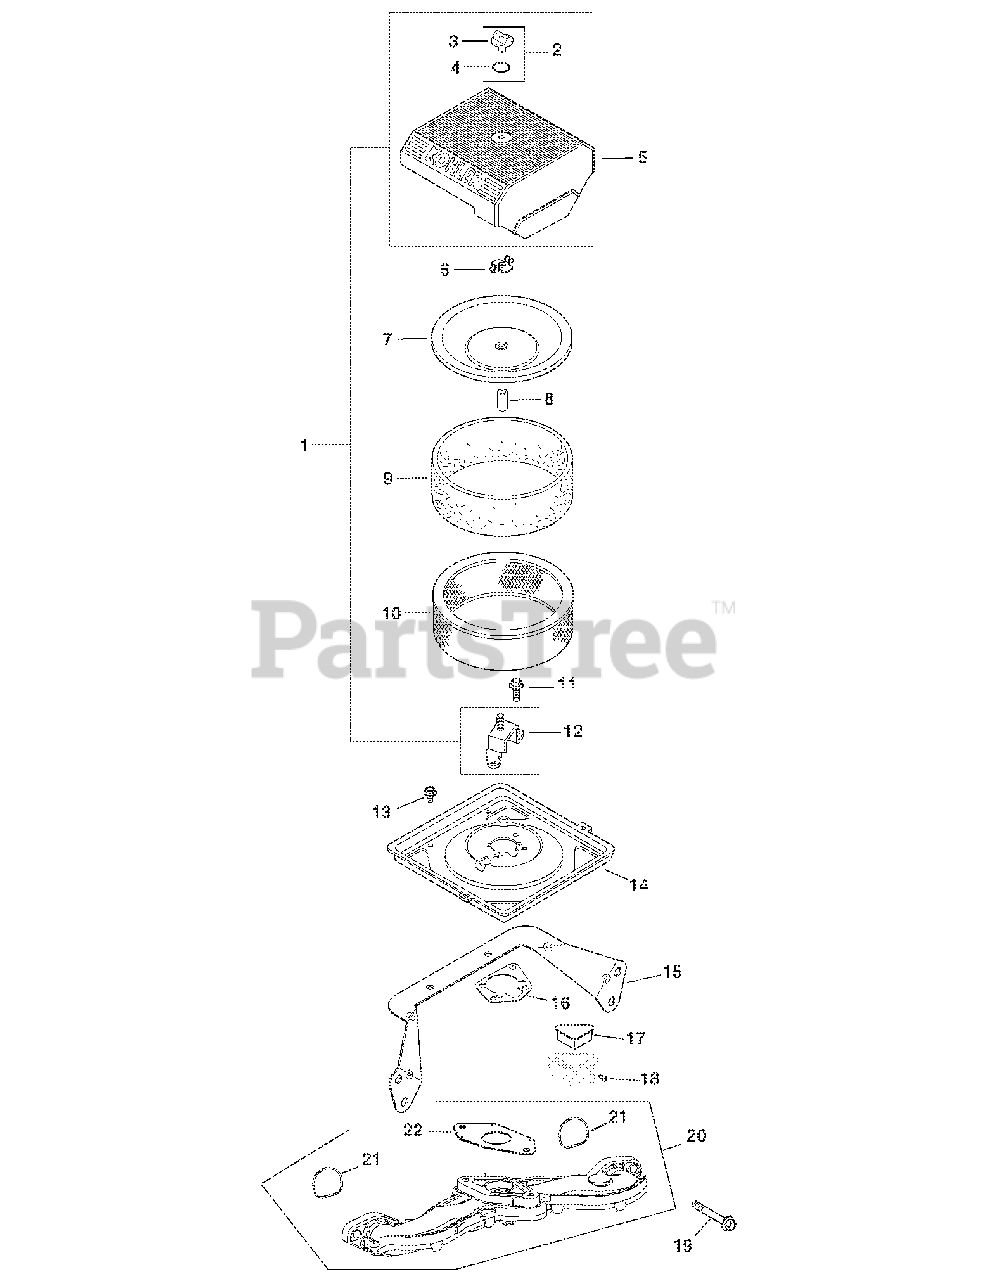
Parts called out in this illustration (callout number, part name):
1	Kit, air cleaner cover
2	Kit, knob w/seal
5	Cover, Air Cleaner
7	Cover, inner air cleaner
8	Seal, inner air cleaner
9	Element, precleaner
10	Element, Air Cleaner
11	Screw, Flange Thrd. Forming M6 x 1.0 x 16
12	Bracket, aircleaner base
13	Screw, flg M5 x 0.8 s 10
14	Base, air cleaner
15	Bracket, air cleaner base
16	Gasket, Air Cleaner Base
17	Cover, blower housing
18	Screw, Wash. Hd. Tapp. #8-18 x .5
19	Screw, flg M6 x 1.0 x 40
20	Manifold, Intake (Includes 21, 22)
21	O-ring, intake port
22	Gasket, carburetor
